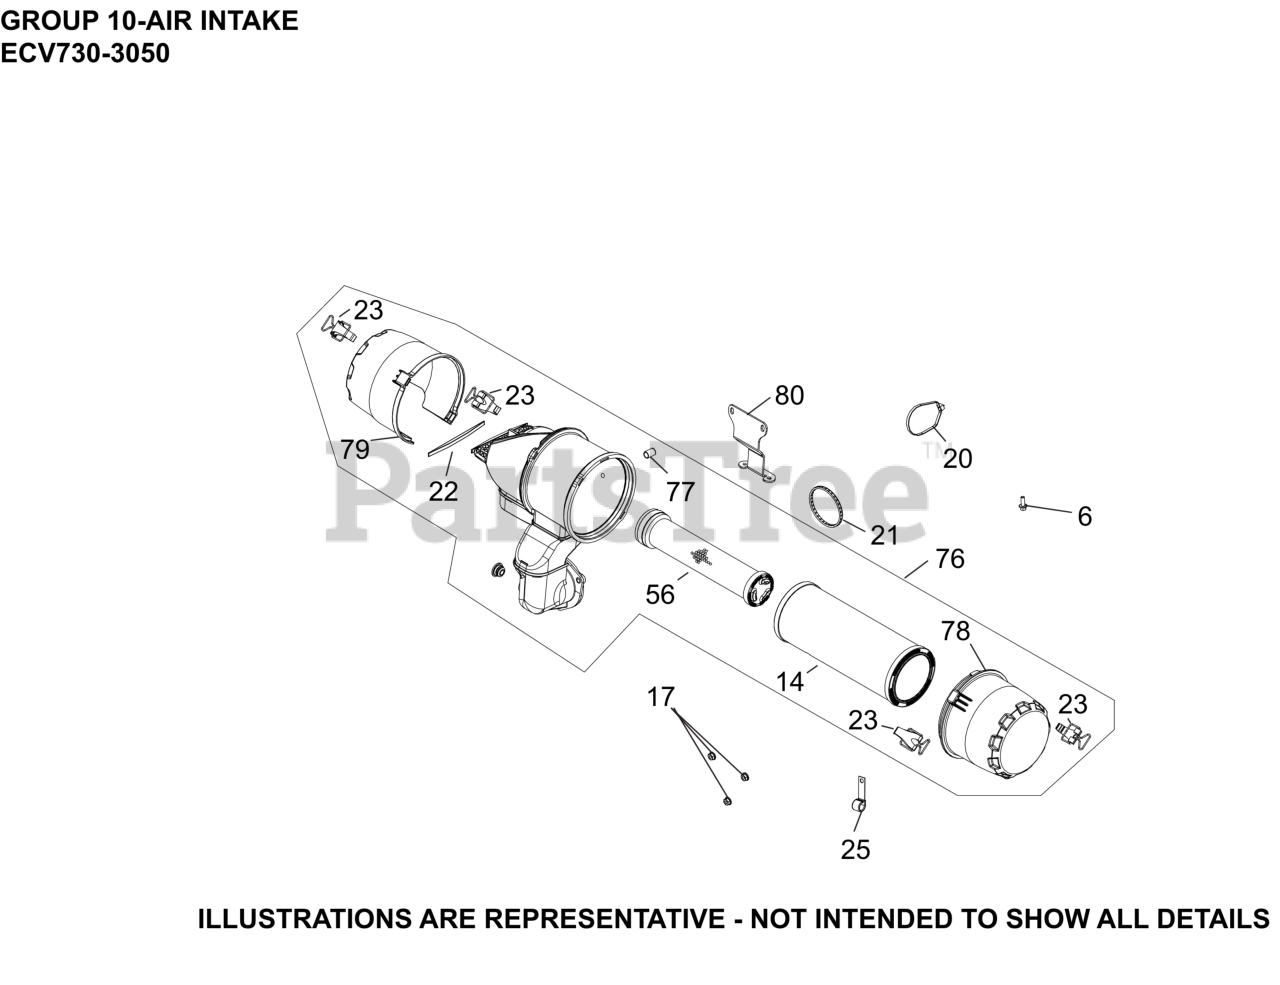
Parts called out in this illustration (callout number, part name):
6	SCREW, FLG M6X1.0X16
14	ELEMENT, AIR FILTER - PRIMARY
17	NUT, FLG M6X1.0
21	O-RING (HDAC SEAL-EFI)
22	DAMPER, FOAM INSERT
23	CLIP ASSEMBLY
25	CLIP, CABLE
56	ELEMENT, AIR FILTER - SAFETY
76	FILTER ASSEMBLY, AIR - OIL FILTER SIDE
77	CAP, MASKING
78	COVER, AIR FILTER
79	COVER, RAIN CAP
80	BRACKET, SUPPORT
